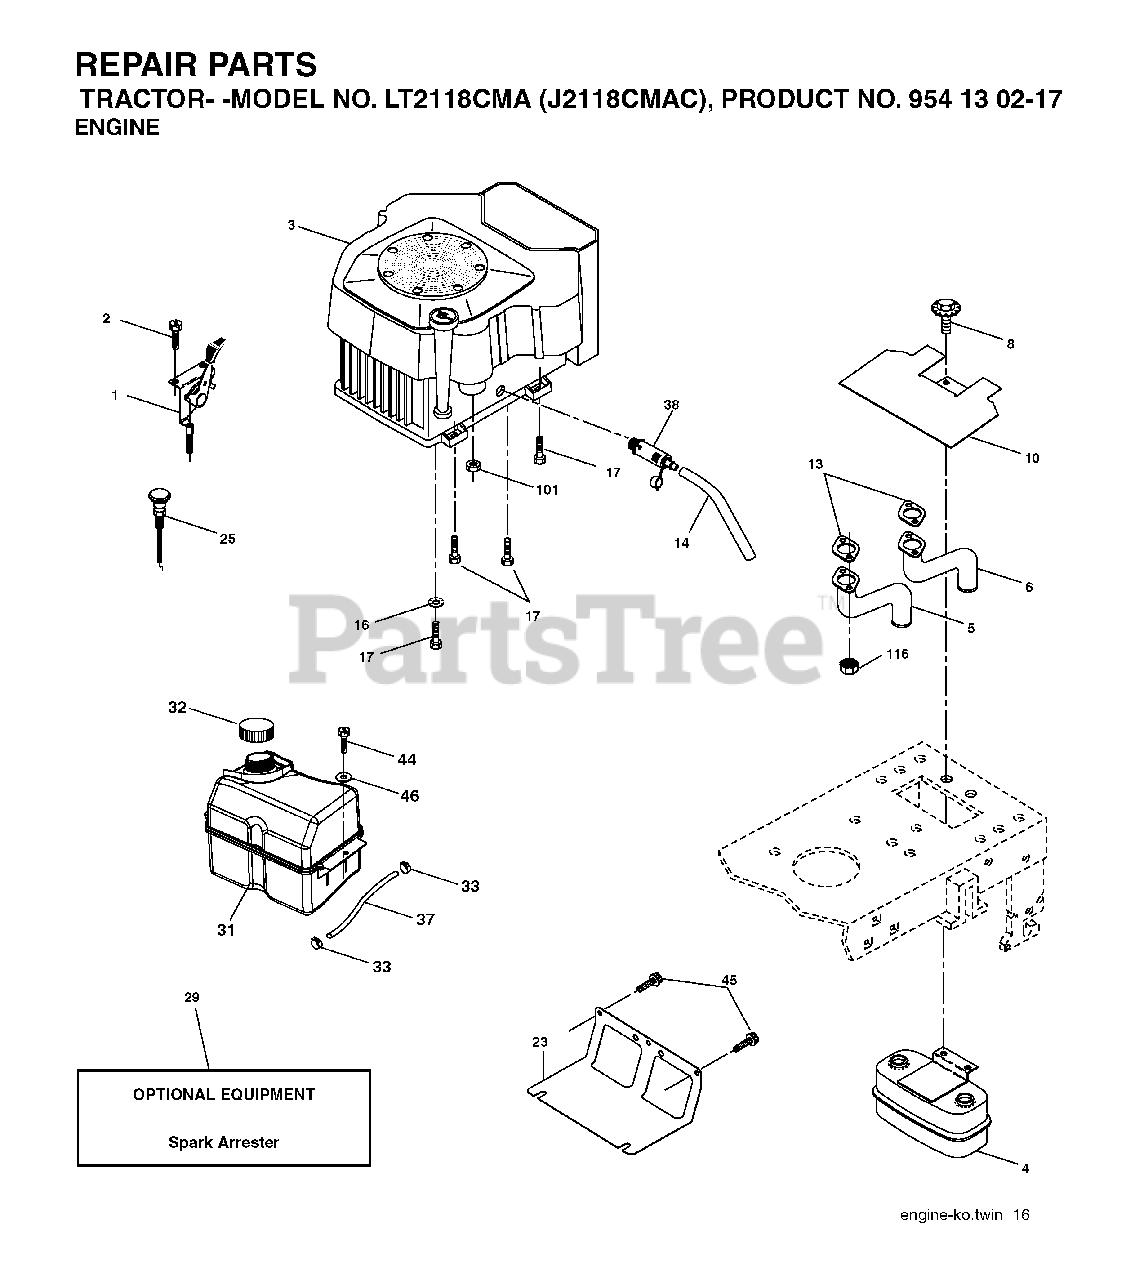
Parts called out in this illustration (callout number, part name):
1	CONTROL.THROTTLE.KAWA
2	SCREW
4	MUFFLER.TWIN.CYL.LOW.TONE
5	PIPE-EXHAUST LH
6	PIPE-EXHAUST RH
8	BOLT, 5/16-18 X 1 3/4
10	RP SHIELD HEAT MUFFLER
14	TUBE, DRAIN OIL ASM.
16	LOCKWASHER
23	SHEILD.BROWNING.DBR.GUARD
25	CONTROL, CHOKE
29	ARRESTER SPARK (OPTIONAL)
31	FUEL TANK
32	FUEL CAP
33	HOSE CLAMP
37	LINE.FUEL.20
38	PLUG DRAIN OIL EASY
44	SCREW HEXWSHR 1/4-20X3/4
45	SCREW, 3/8-16X3/4
101	FLANGE NUT
116	NUT.HEX.FLANGE.TOPLOCK
